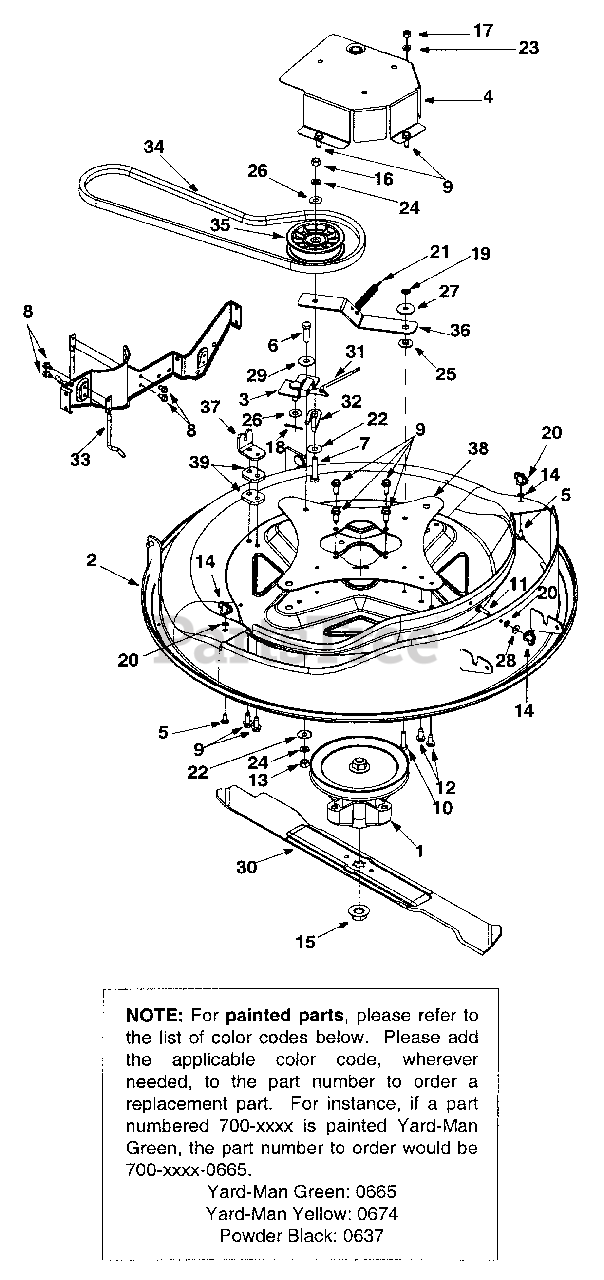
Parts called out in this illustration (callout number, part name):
1	Spindle Assembly
5	Carriage Screw 1/4-20 x .62
6	Hex Bolt 3/8-24 x 1.25 Grade 8
7	Hex Screw 3/8-16 x 1.75 Gr. 5
8	Self-Tapp. Screw 1/4-20 x.5
9	Self-Tapp. Screw 5/16-18 x .75
10	Hex Cap Scr. 5/16-24 x 1.25
11	Carriage Screw
12	Torx Screw 5/16-18 x .75
13	Hex Nut 3/8-24
14	Wing Nut With Bell Washer
15	Flange Nut 5/8-18
16	Hex Nut 3/8-16
17	Hex Nut 5/16-24
18	Cotter Pin
19	Speed Nut
20	Push Nut
21	Extension Spring
22	Flat Washer 3/8 x 1.00 x .030
23	Lock Washer 5/16
24	Lock Washer 3/8
25	Bushing
26	Flat Washer .406 x .875 x .059
27	Flat Washer .330 x 1.25 x .120
28	Flat Washer
29	Spacer
32	Belt Keeper
35	Flat Idler Pulley
